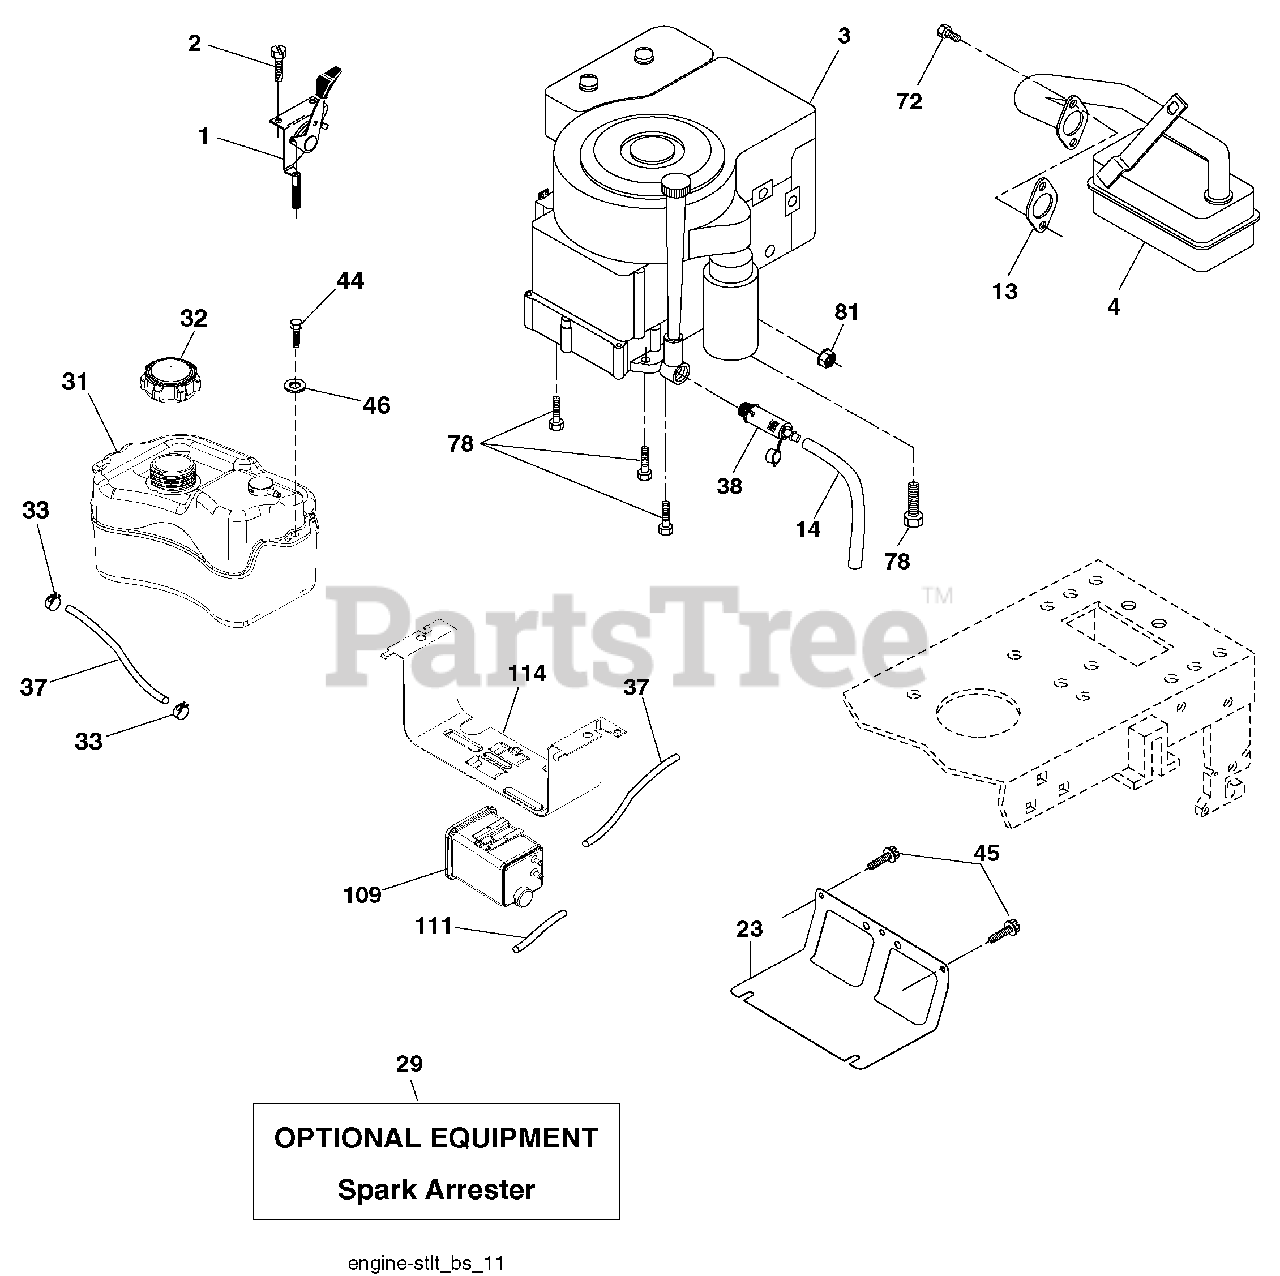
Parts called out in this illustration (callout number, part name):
1	Control Th/ch Flag
2	Screw Hex Thd Cut 1/4-20 x 1/2
4	Muffler Exhaust B&S
13	Gasket Eng 1 313 Id Tin Plated
14	Tube Drain Oil Easy
23	Shield BRN/DBR Guard
29	Kit Spark Arrestor (Flat Scrn)
31	Tank Fuel Front
32	Cap Asm Fuel
33	Clamp Hose
37	Line Fuel
38	Plug Drain Oil
44	Screw Thdrol 1/4-20 x 3/4
45	Screw Hex Wsh Thdrol 3/8-16
46	Washer 9/32 x 7/8 x 16 Ga.
72	Screw Socket Head 5/16-18 x 3/4
78	Screw 3/8-16 x 1-1/4
81	Nut Keps Hex 1/4-20 unc
109	Canister Carbon Filter Asm.
111	Purge Line
114	Cradle Canister Carbon
